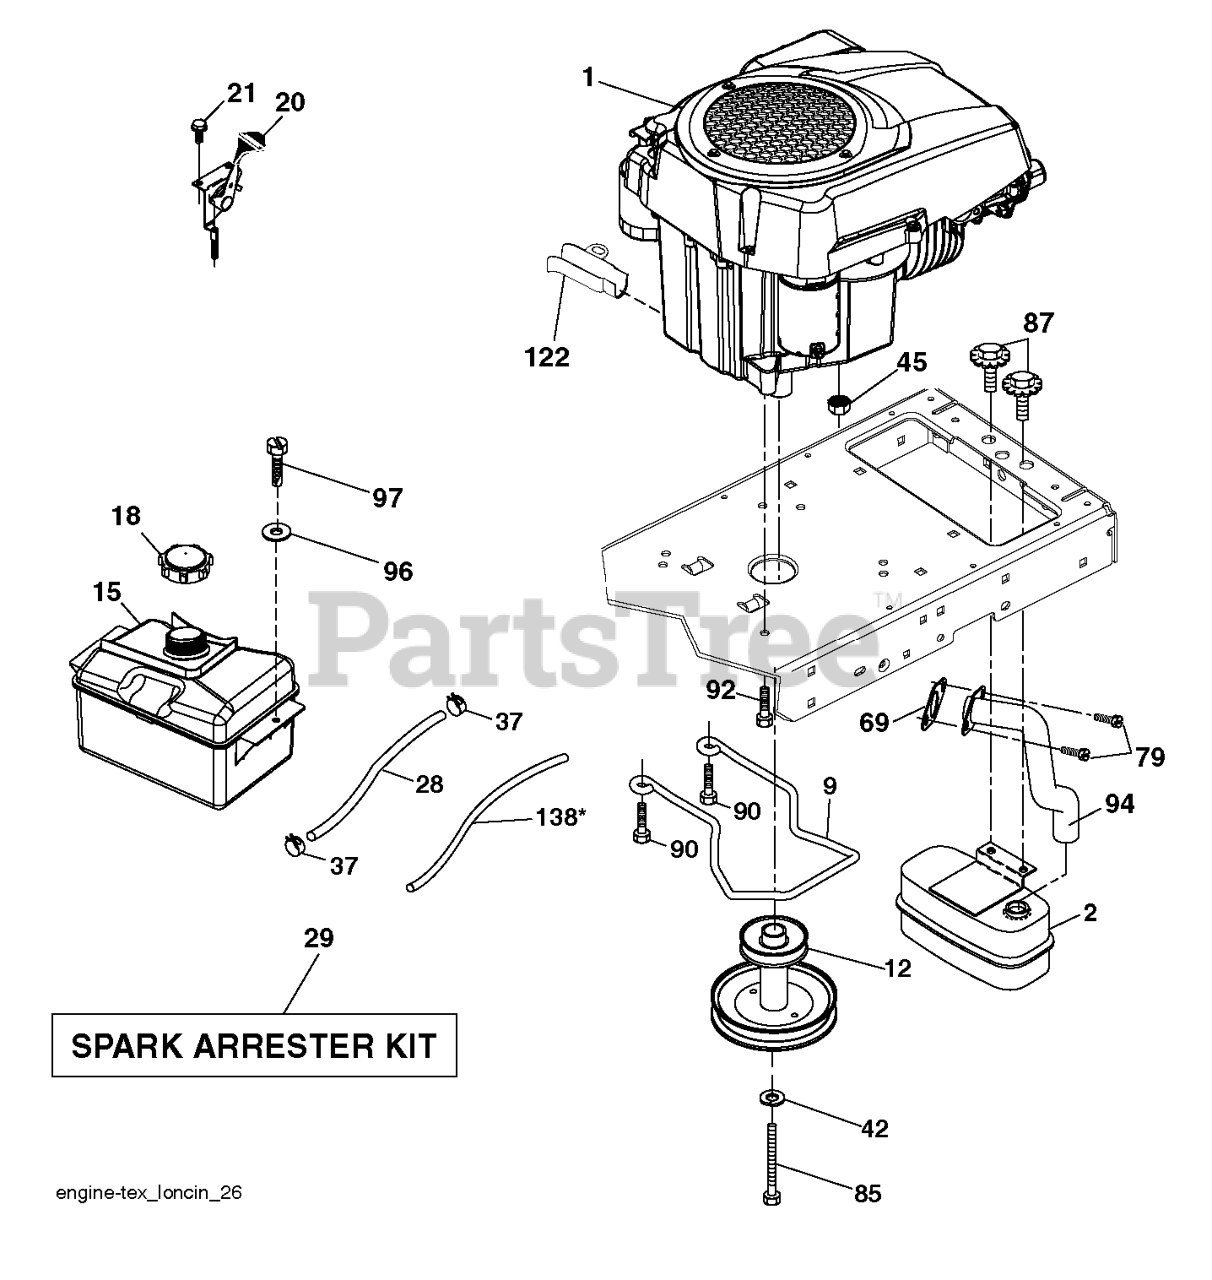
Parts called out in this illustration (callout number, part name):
1	DECK W/DECALS 42"
2	E-RING 1/2 (2 2)
5	BLADE OEM, 14-7/8
6	HOUSING, COMPLETE
7	MACHINERY BUSHING 10 GA.
9	BEARING
10	HOUSING, DIE CAST
11	SPINDLE SHAFT
13	HCS 5/16C X 1 1/4
14	HCS 5/8F X 1 1/4
15	LOCKWASHER 5/8
16	DISCHARGE CHUTE 42"
17	HCS 5/16C X 3/4
19	CARRIAGE BOLT 5/16C X 5/8"
20	CENTER BAFFLE
21	WASHER 5/16 FLAT
22	NUT 5/16 CTR. LOCK
23	MAIN BAFFLE
24	STRUT WLDMT - RT
25	ZERK
26	HCS 5/8C X 2 GR.5
27	STRUT MOUNT WELDMENT
28	HCS 7/16C X 1 1/2
29	LIFT CHAIN
30	NUT 7/16C CENTERLOCK
31	NUT 7/16C WHIZ
32	HCS 7/16F X 1 1/2
33	WASHER 7/16 LOCK
34	SPINDLE WASHER
35	KEY 1/4 SQ X 1 1/8
37	IDLER PULLEY (TALL)
38	NUT 3/8-16 NYLOC
39	WASHER 3/8 FLAT
40	IDLER BUSHING
41	IDLER PULLEY
43	4CS 3/8C X 1 SERRATED HEAD
44	NUT 1/2-13 HEX NYLOC ZD
45	WASHER 1/2 FLAT
47	PIVOT BUSHING
48	BELT SHIELD
49	WASHER, SUPPORT
50	HCS 1/2C X 3 1/4
51	SCREW 3/8C X 2 3/4 HEX CAP
52	NUT 5/16C CENTERLOCK
53	DECAL, NO STEP
54	DECAL, CPSC
55	DECAL, DANGER
539103240	BELT, DECK 42"
539104621	STRUT SLDMT-LT
